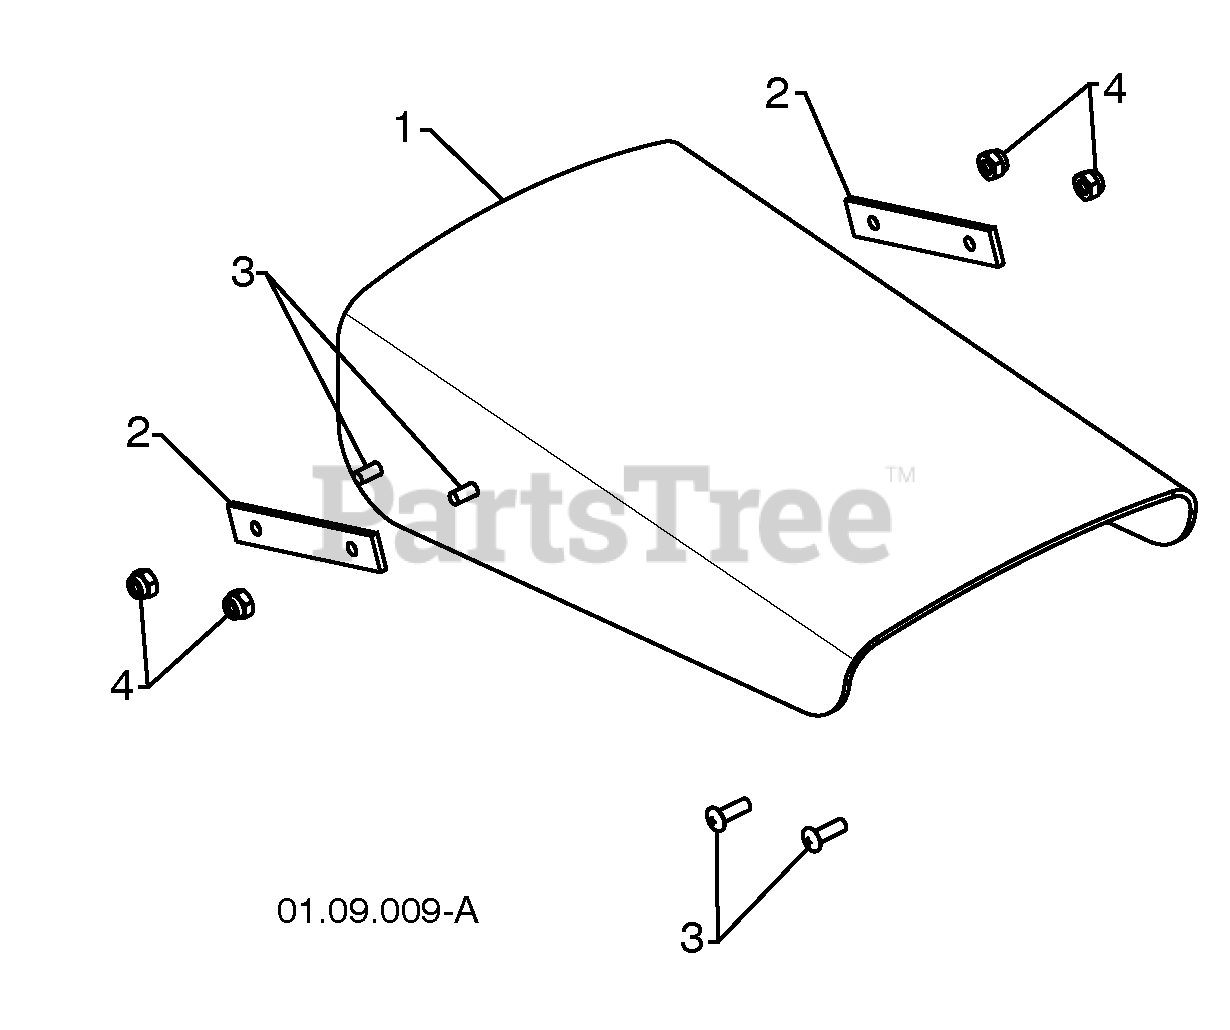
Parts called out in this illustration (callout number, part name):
1	SHIELD DEFLECTOR
2	STRAP
3	SCREW 8-32 X .50
